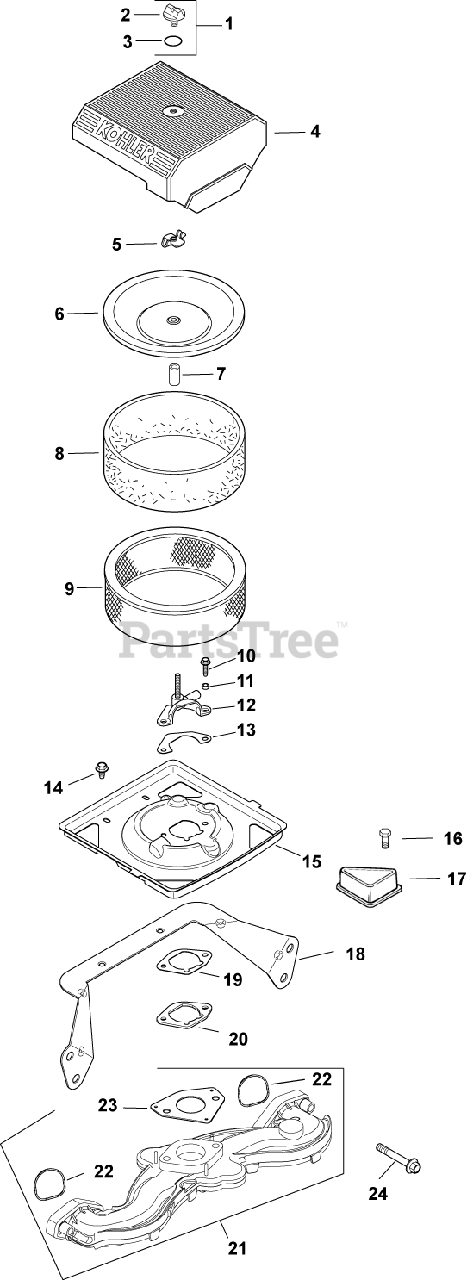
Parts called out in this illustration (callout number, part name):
1	KIT, KNOB W/SEAL
2	KNOB, COVER
4	COVER, AIR CLEANER
5	NUT, WING
6	COVER, INNER AIR CLEANER
7	SEAL, INNER AIR CLEANER
8	ELEMENT, PRECLEANER (LOW)
9	ELEMENT, AIR CLEANER - Also available Retail Packaged 47 883 03-S1 Air Filter Kit
10	SCREW, FLG THD FRM M5X.8X20-(#25086399S)
12	CUP, FUEL SPITBACK W/NIPPLE
13	GASKET, FUEL SPITBACK CUP
14	SCREW, FLG THD FRM M5X.8X10
15	BASE, AIR CLEANER-USE 24 094 86-S
16	SCREW, WSH HD TAP #8-18X1/2"
17	COVER, BLOWER HOUSING USE 24 096 160-S
18	BRACKET, AIR CLEANER BASE
19	GASKET, AIR CLEANER BASE
20	SPACER, AIR CLEANER BASE
21	MANIFOLD, INTAKE - PLASTIC-USE 24 164 91
22	O-RING, INTAKE PORT
23	GASKET, CARBURETOR
24	SCREW, FLG M6X1.0X40
